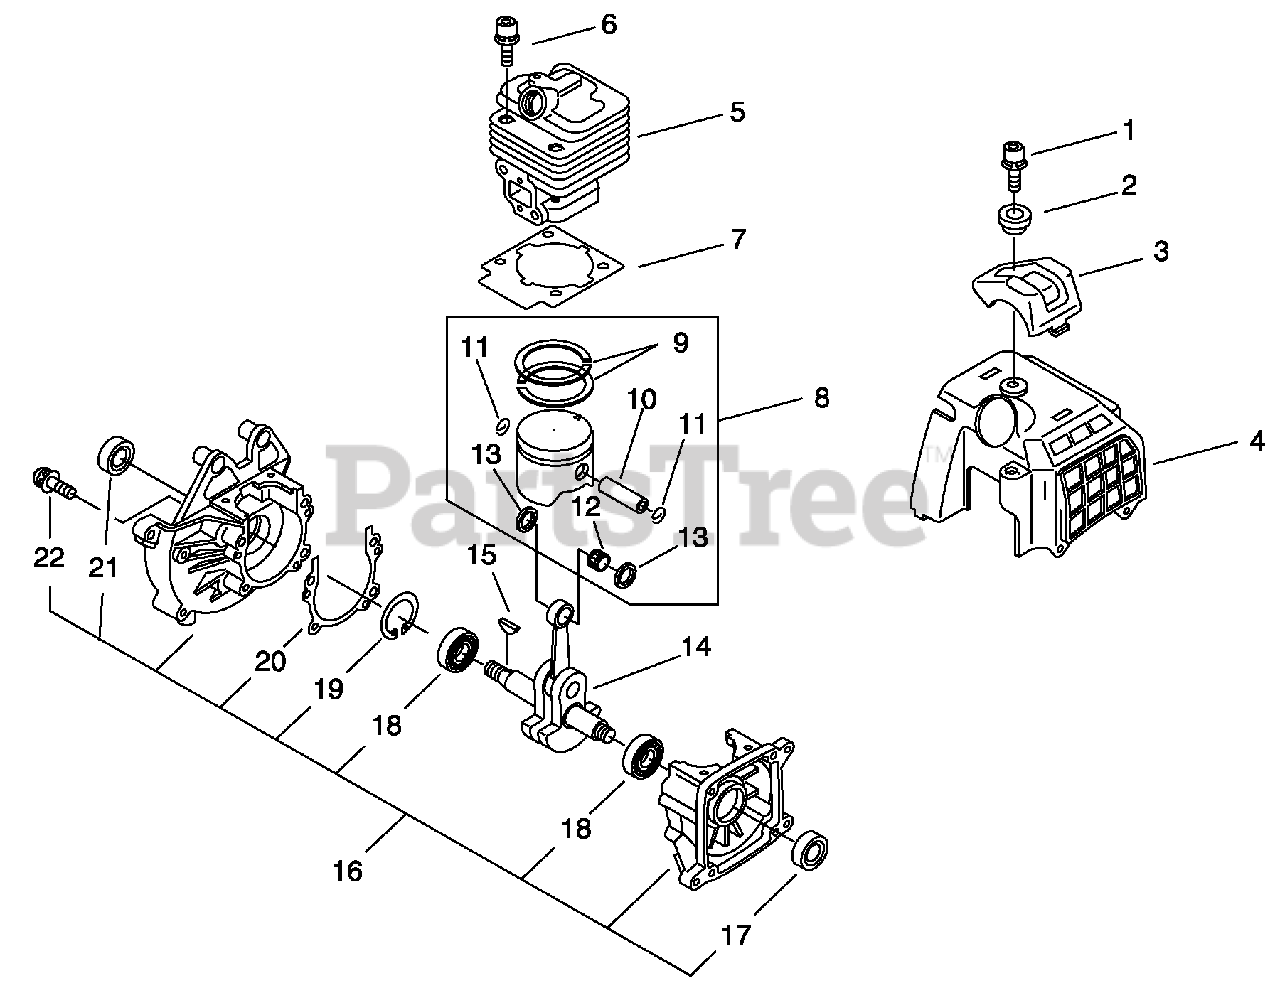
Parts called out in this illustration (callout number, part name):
1	BOLT, FLANGE
2	COLLAR 5
3	GUARD, TOP
4	COVER, ENGINE
5	CYLINDER
6	BOLT 5×22
7	GASKET, CYLINDER
8	PISTON KIT
9	RING, PISTON
10	PIN, PISTON
11	RING, SNAP
12	BEARING, NEEDLE 8
13	WASHER, THRUST
14	CRANKSHAFT ASSY
15	KEY, WOODRUFF
16	CRANKCASE KIT
17	SEAL, OIL 12
18	BEARING, BALL 6001
19	RING, SNAP 28
20	GASKET, CRANKCASE
21	SEAL, OIL 12
22	BOLT 5×25
